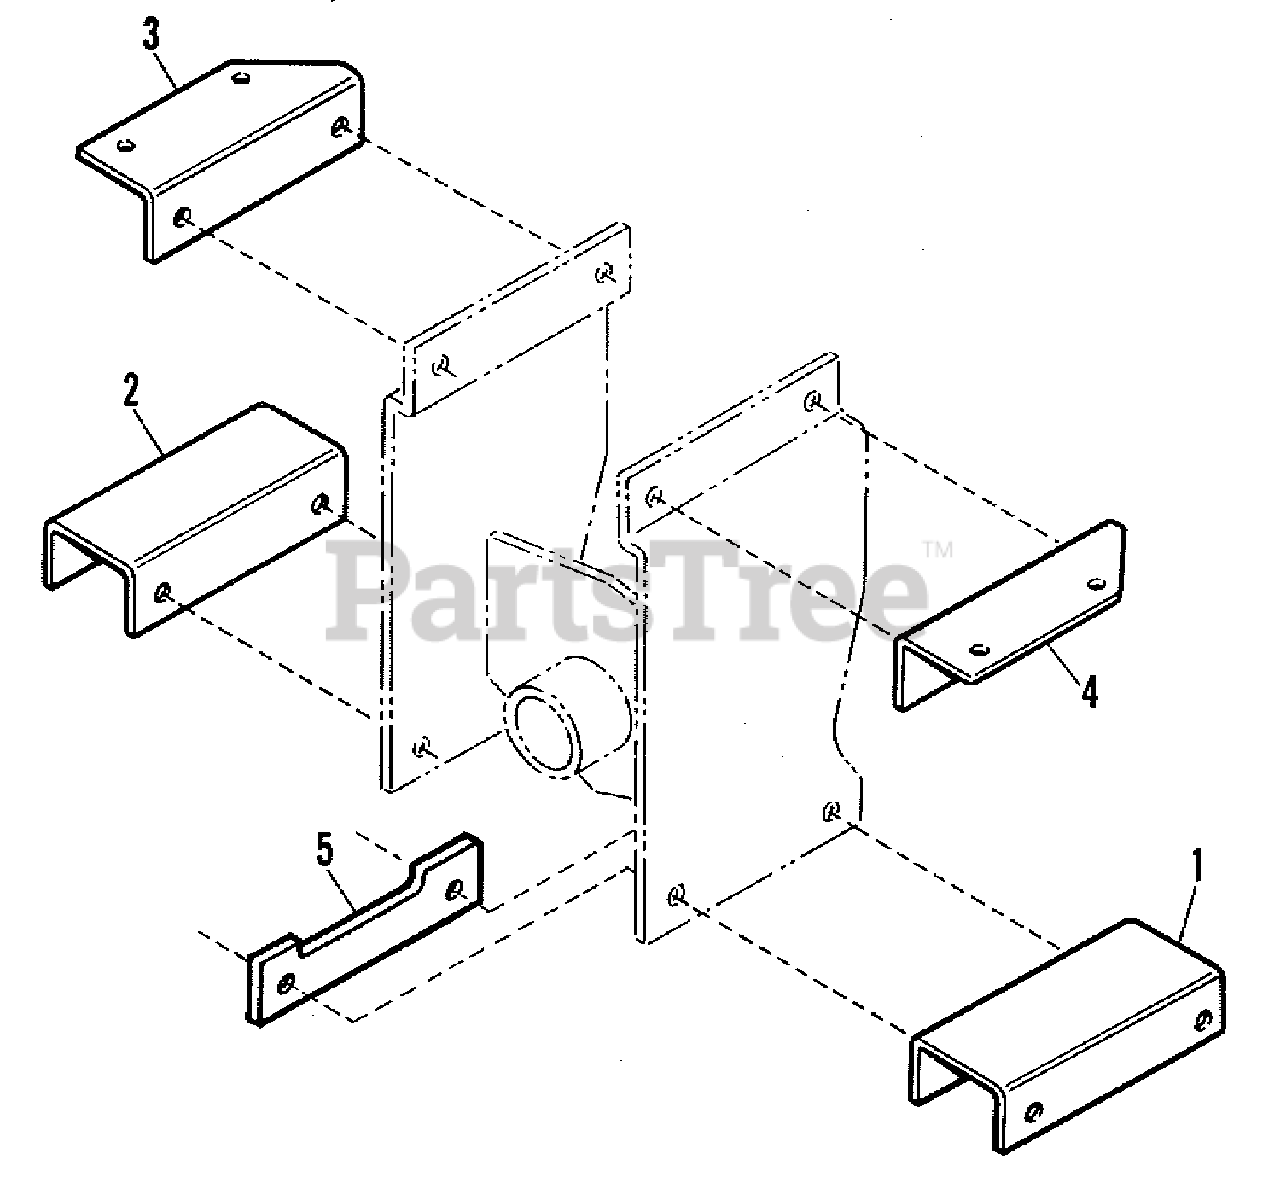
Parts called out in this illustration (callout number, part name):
1	SUPPORT ASSEMBLY, Clutch, L.H. (5030)
1	CAPSCREW, 1/2NC x 1-1/2
1	LOCKWASHER, 1/2
2	SUPPORT ASSEMBLY, Clutch, R.H. (5030)
2	CAPSCREW, 1/2NC x 1-1/2
2	LOCKWASHER, 1/2
3	ANGLE, Battery Support, L.H. (5030)
3	CAPSCREW, 5/16NC x 1
3	LOCKWASHER, 5/16
3	NUT, 5/16NC
4	ANGLE, Battery Support, R.H. (5030)
4	CAPSCREW, 5/16NC x 1
4	LOCKWASHER, 5/16
4	NUT, 5/16NC
5	SPACER (For 5020 w/FWD)
5	CAPSCREW, 1/2NC x 1-3/4
5	LOCKWASHER, 1/2
